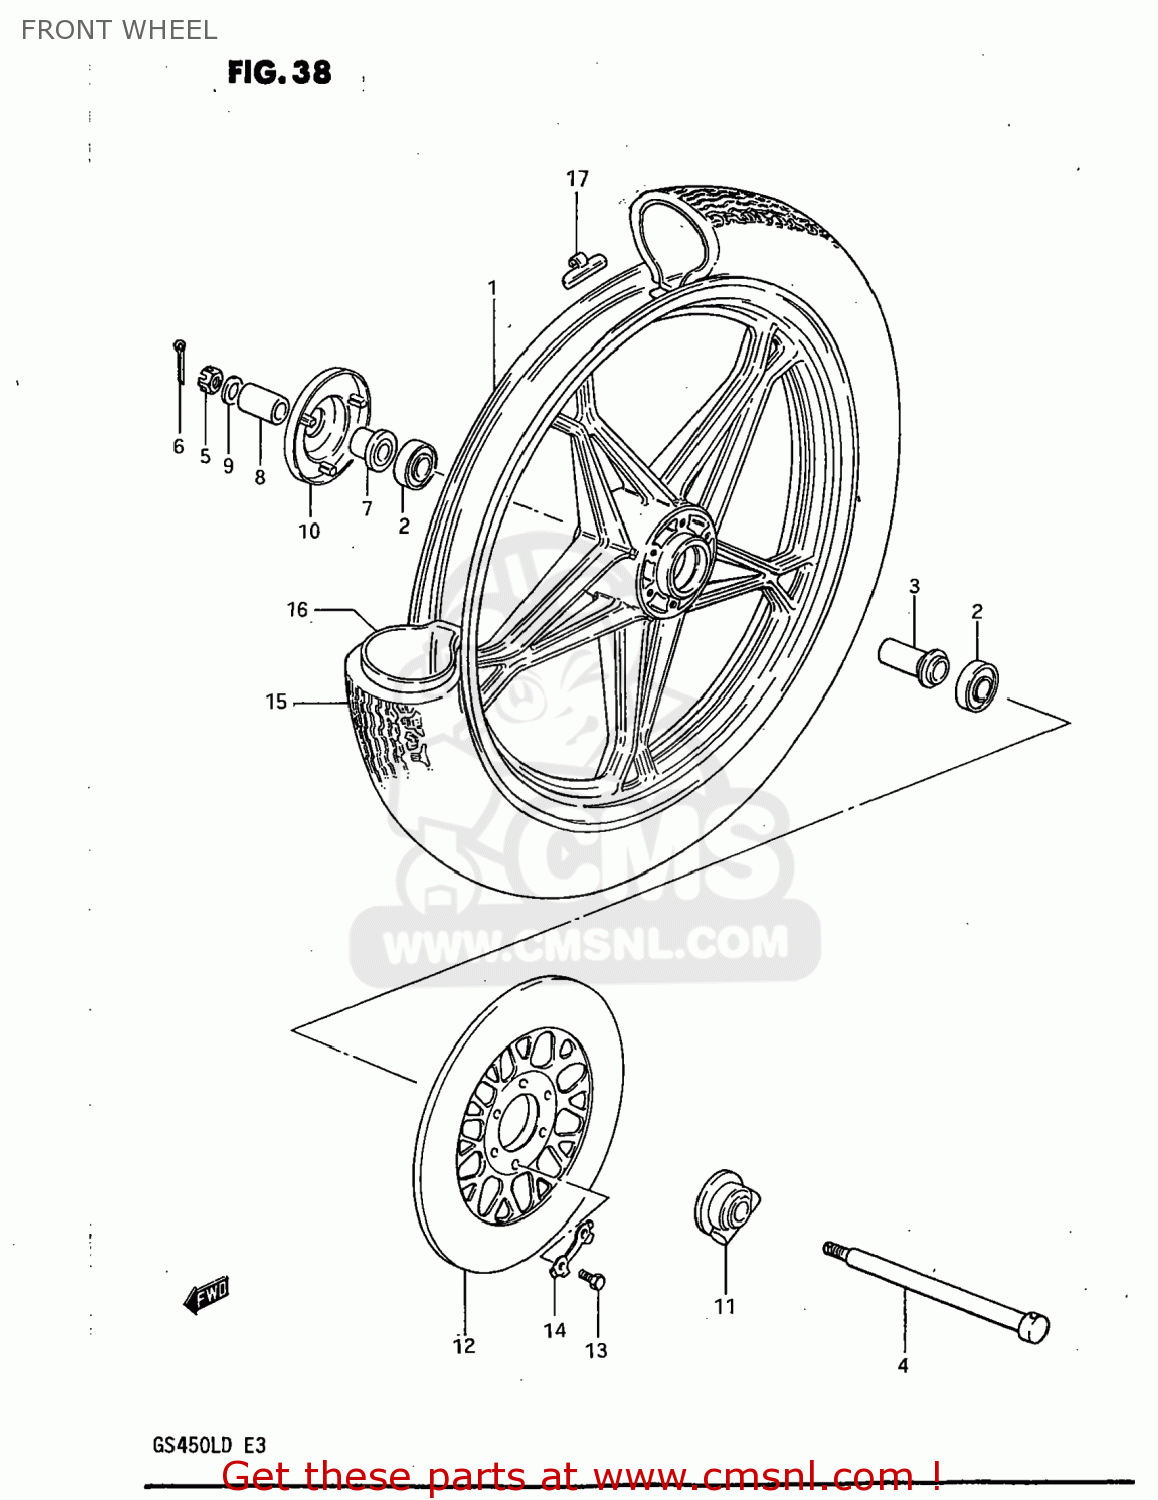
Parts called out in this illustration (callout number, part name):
1	CASTING WHEEL,FRONT 1.85
2	BEARING
3	SPACER,FR HUB BEARING
4	AXLE,FRONT
5	NUT 12MM
6	COTTER PIN
7	SPACER,FR HUB BEARING,R
8	SPACER(15X22X30)
9	WASHER
10	COVER,FR HUB,R
11	BOX ASSEMBLY,SPEEDOMETER GEAR
12	DISC,FR BRAKE
13	BOLT(8X25)
14	WASHER
15	TIRE
16	TUBE 2.75-19 070-483MM
17	BALANCER,WHEEL
